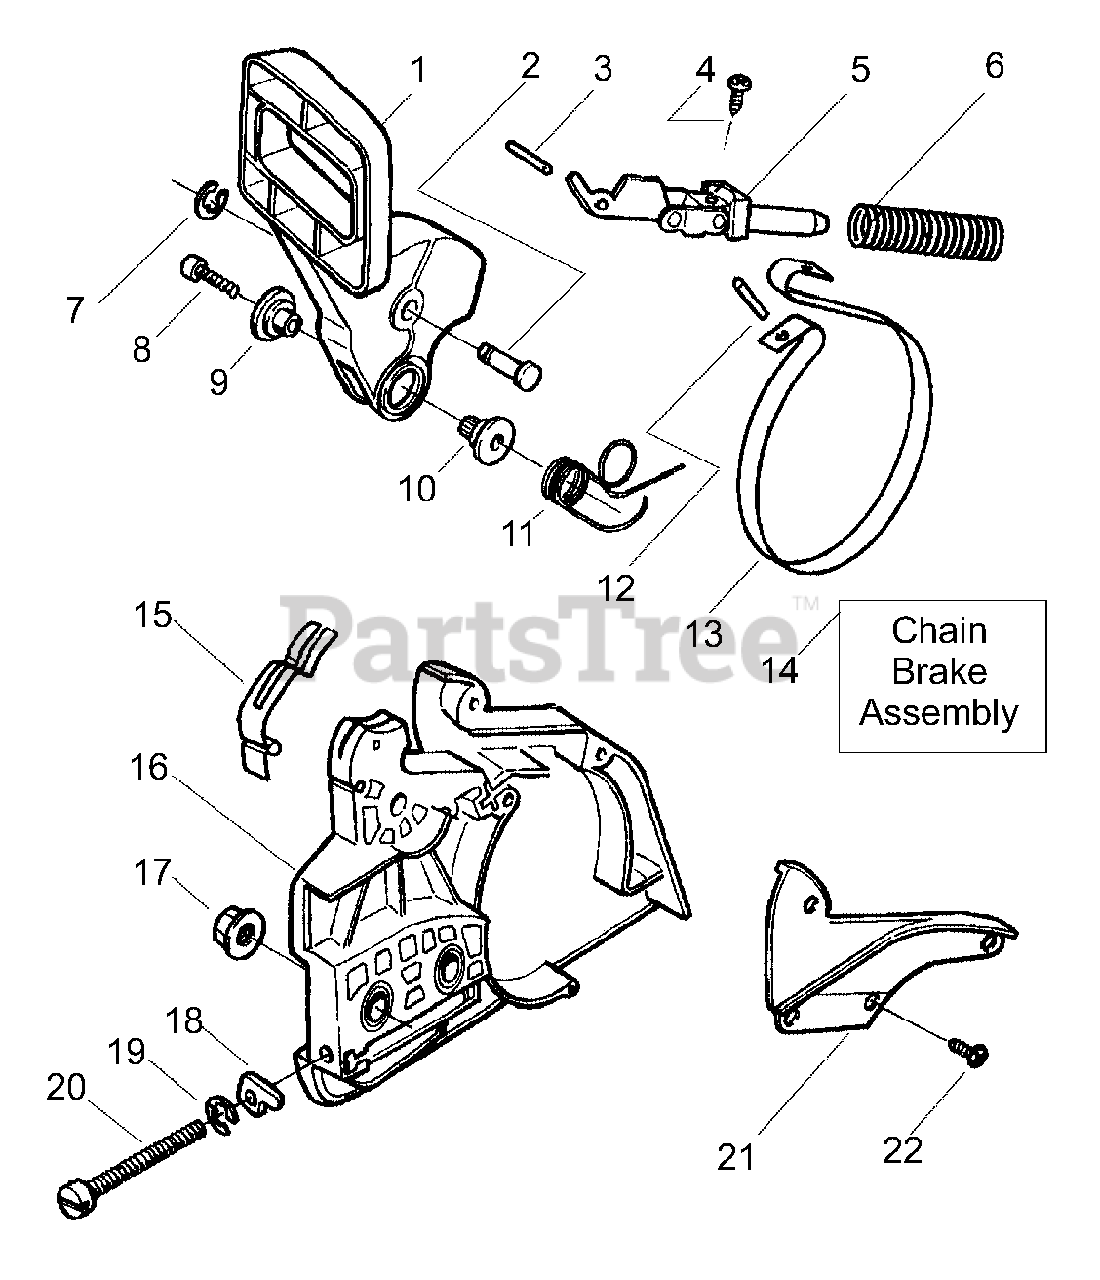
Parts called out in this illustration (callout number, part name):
1	Actuating Lever
3	Straight Pin
5	Front Link Ass'y.
6	Chain Brake Spring
9	Right Pivot Sleeve
10	Left Pivot Sleeve
11	Handguard Spring
13	Brake Band
14	Chain Brake Assembly
15	Position Spring
16	Clutch Cover
18	Bar Adjusting Pin
20	Screw-Bar Adjusting
21	Chain Brake Spring Cover
